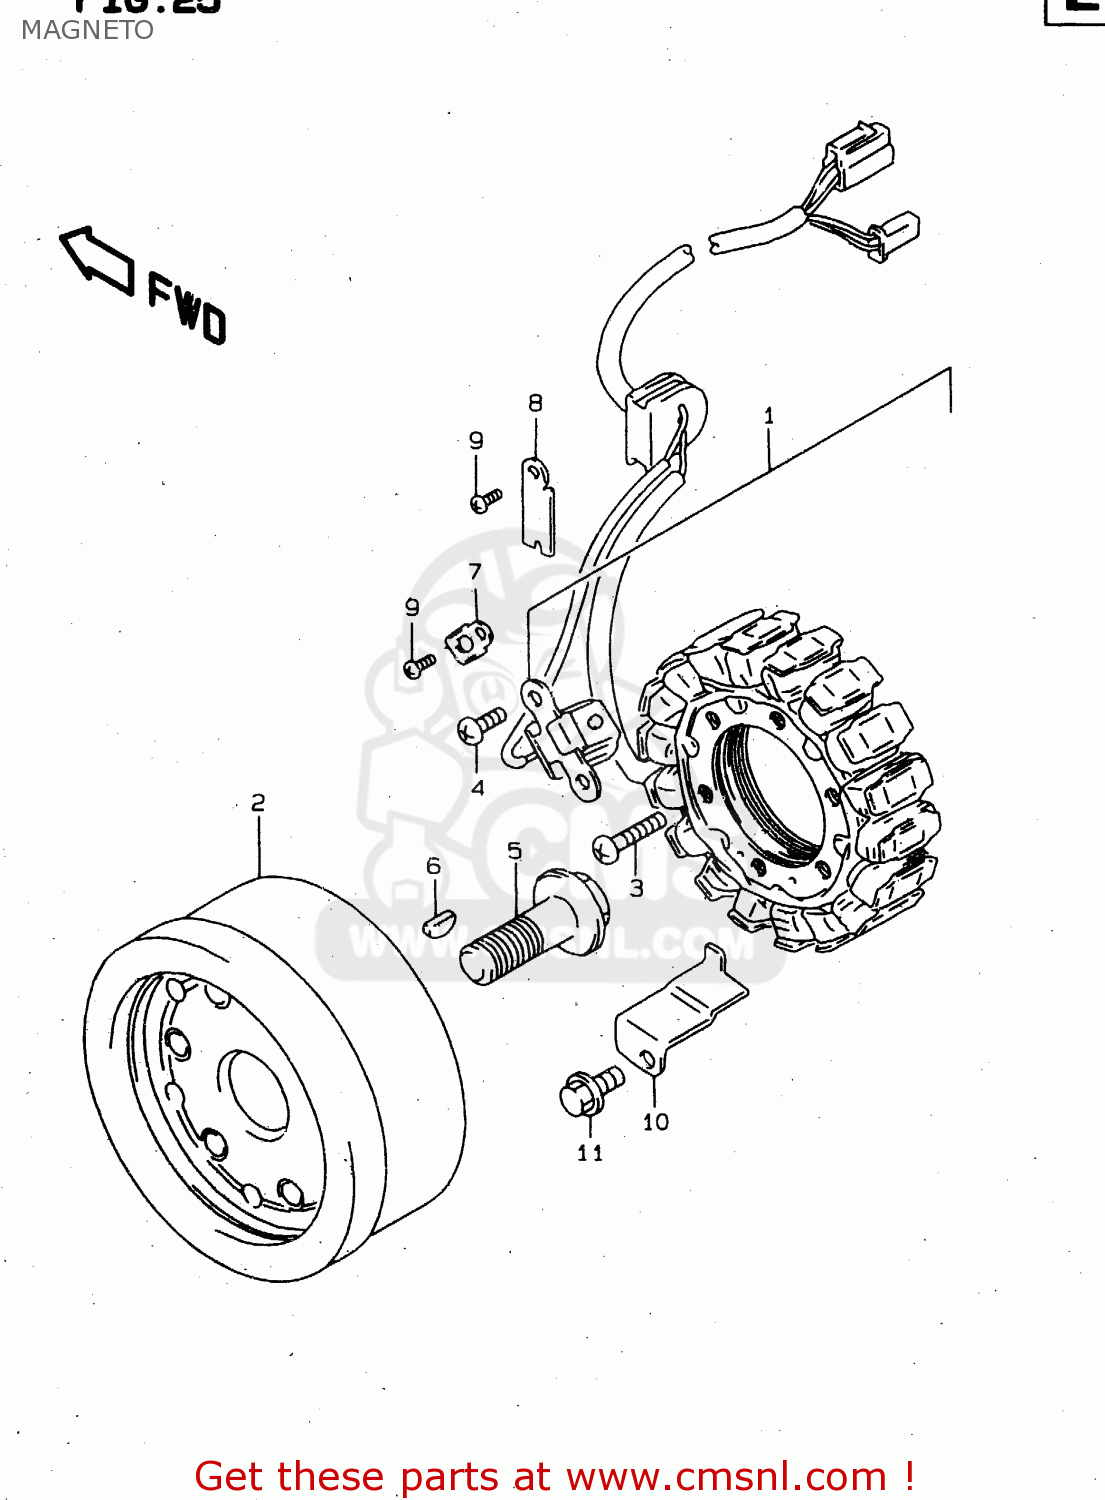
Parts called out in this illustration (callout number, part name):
1	STARTER ASSY
2	ROTOR ASSY
3	BOLT,G/S SWITC
4	SCREW
5	BOLT(14X43)
6	KEY
7	CLAMP,GENERATOR LEAD WIRE
8	CLAMP NO.1,MAGNETO READ WIRE
9	SCREW
10	CLAMP,MAGNETO LEAD WIRE
11	BOLT
